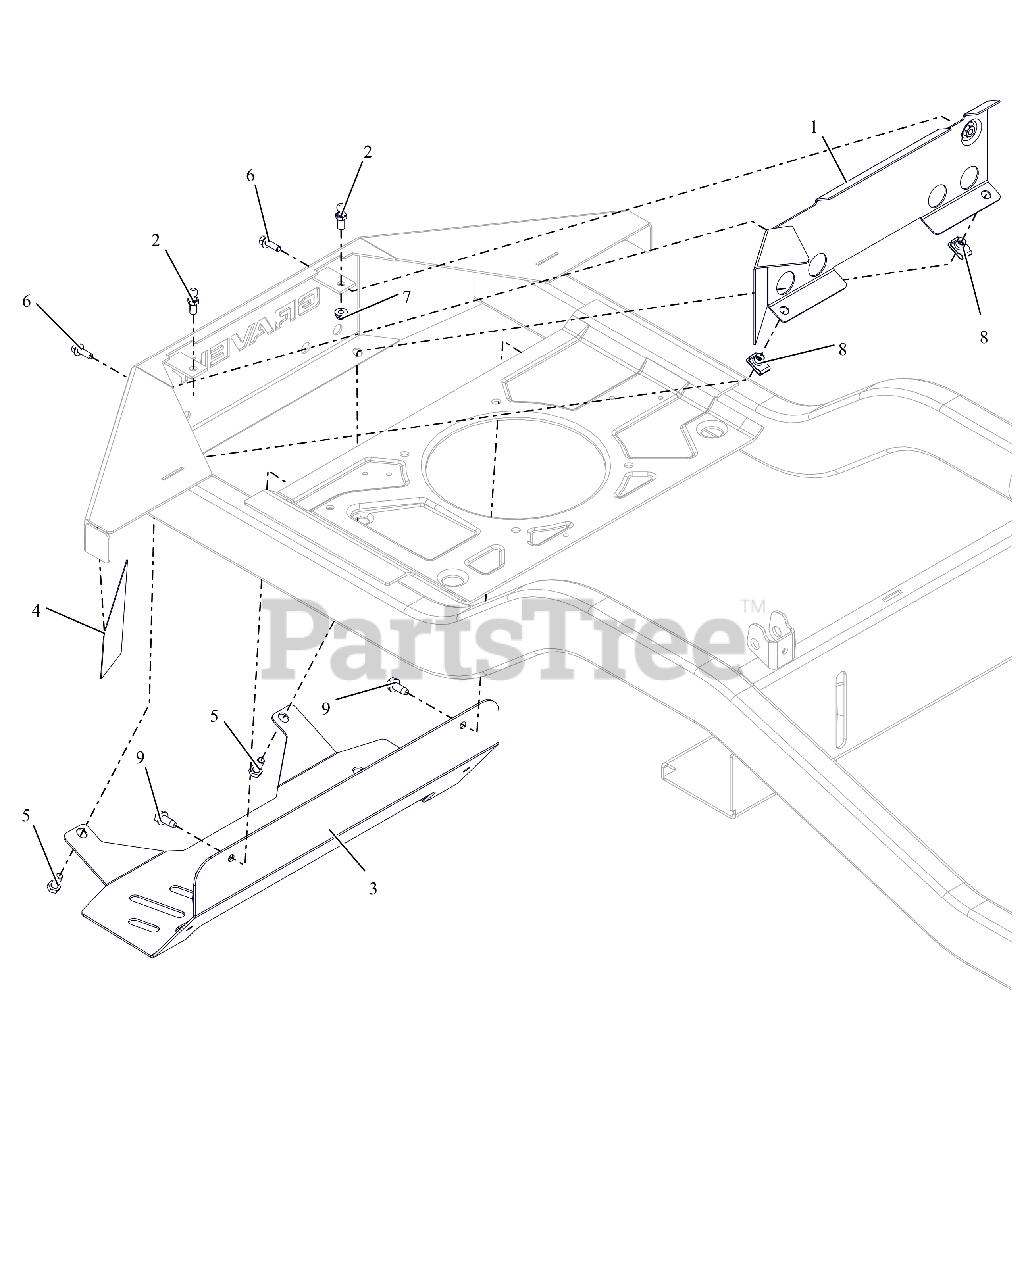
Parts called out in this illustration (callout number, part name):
1	WMT, HEAT BAFFLE
2	STUD- BALL
3	SHIELD, HEAT (HD)
4	TAPE, HEAT DEFLECTOR
5	BLT,HEX .31-18X.75 G5 ZCC
6	BLT,HEX-FLG .25-20X.75 G5 BFP
7	NUT,NYL-FLG .25-20 GF ZCC
8	NUT-CLIP RETAINER 5/16-18X.56
9	SCR,TAP .312-18X.75 HWH TR ZCC
